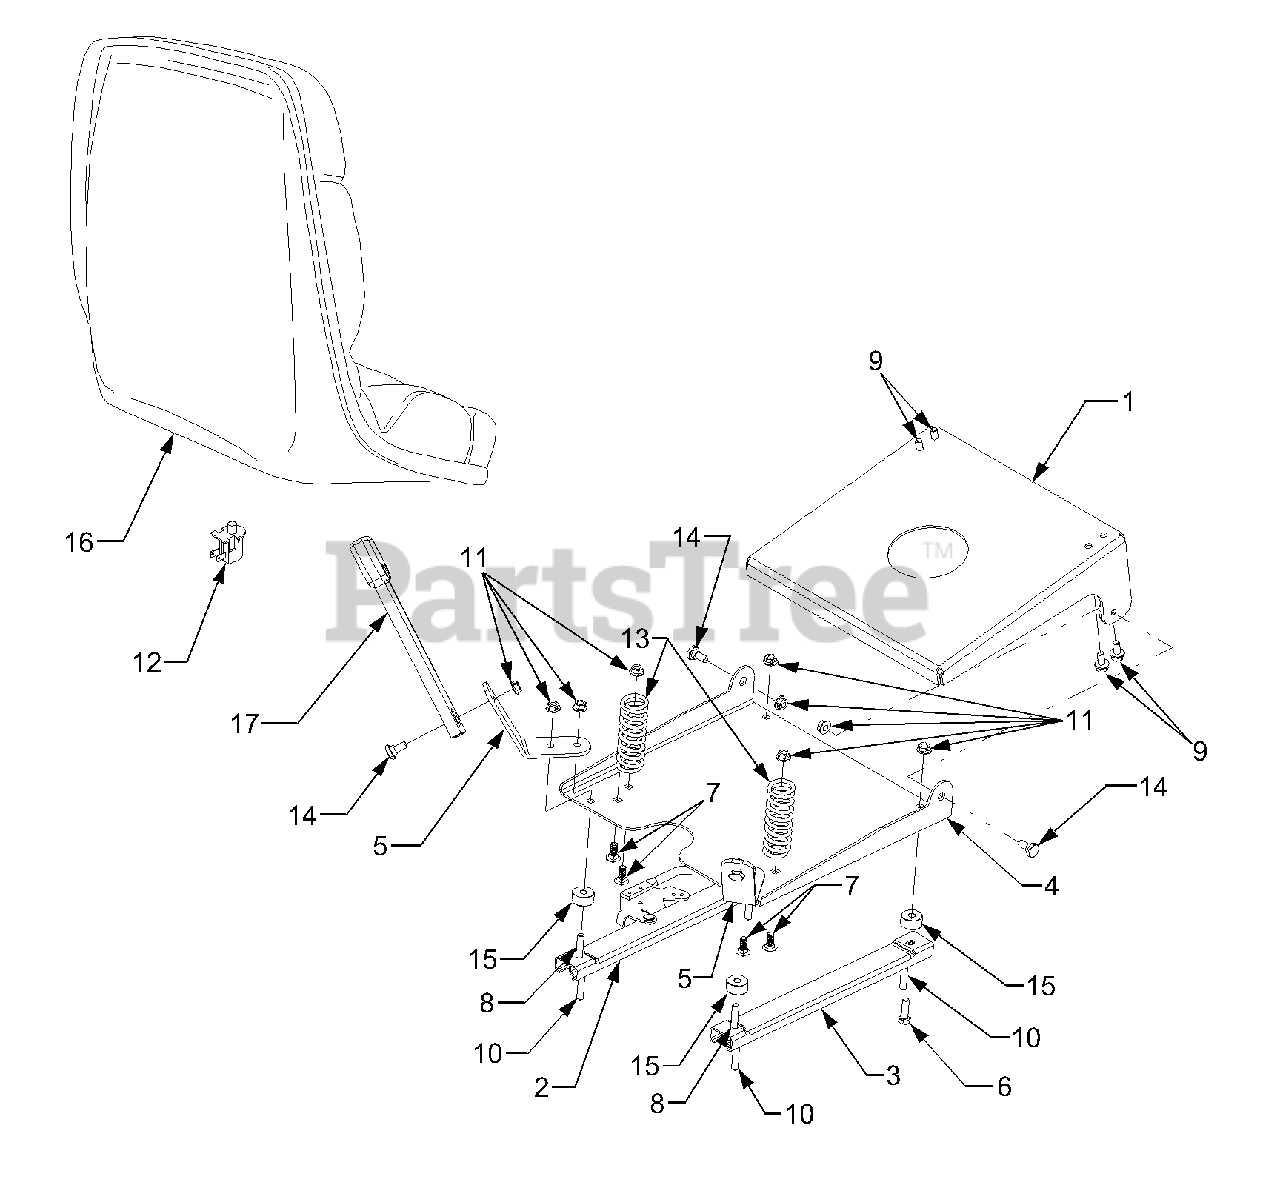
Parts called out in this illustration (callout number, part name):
1	Support, Seat - Upper
2	Track Ass'y., Seat w/Latch
3	Track Ass'y., Seat w/o Latch
4	Tray, Lower Seat
5	Bracket, Seat Belt
6	Screw, Hex Cap, 5/16-18 x 1.0 GR5
7	Screw, Carriage, 5/16-18 x .75
8	Screw, Hex Cap, 5/16-18 x 1.25 GR5
9	Screw, Hex Flange, 5/16-18 x .625 GR5
10	Screw, Socket Hd Cap, 5/16-18 x 1.5
11	Nut, Hex Flange Lock, 5/16-18
12	Switch, Snap Mount (N.O.)
13	Spring, Compression, 1.28 x 3.5
14	Screw, Shoulder, .435 x .178-5/16-18
15	Spacer, .315 x .750 x .375
16	Seat, High Back
17	Belt Assembly, Seat
